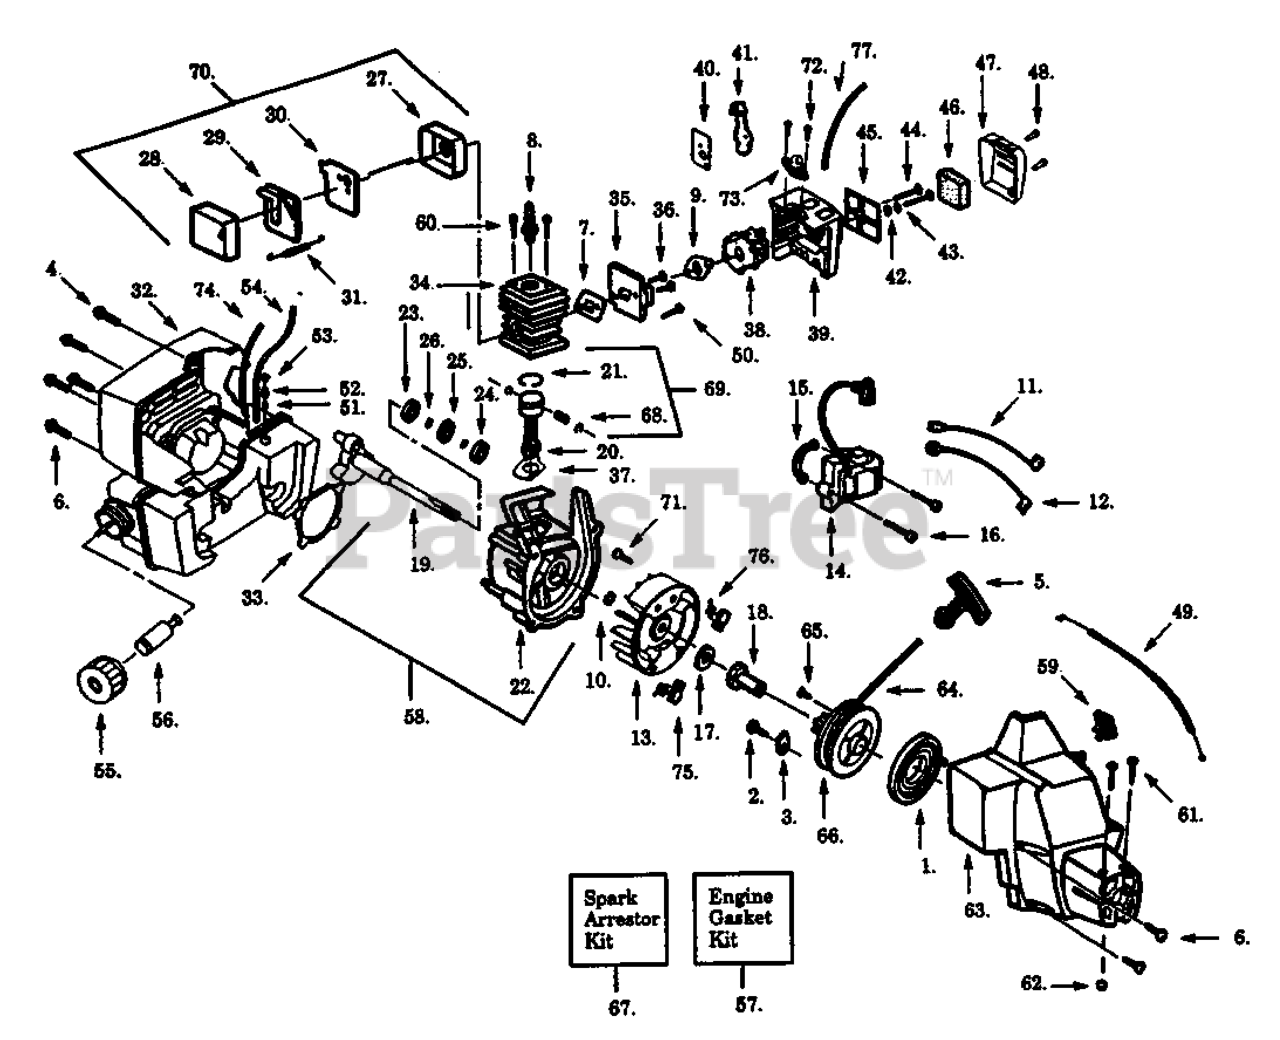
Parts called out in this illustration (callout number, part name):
1	SPRING-STARTER
2	SCREW 8-16 X 9/16 (PLAS
5	HANDLE-STARTER
6	SCREW - SHROUD
7	GASKET
8	Spark Plug (Model GF26 (RCJ-SY))
9	GASKET - CARBURETOR
12	GROUND WIRE
13	FLYWHEEL
14	IGNITION MODULE
15	SPACER - IGNITION MODULE
17	WASHER FLAT
18	COUPLING-DRIVE
19	Cranshaft Ass'y.
20	CONNECTING ROD ASSEMBLY
21	PISTON RING
22	CRANKCASE ASSY
25	SEALING RING
26	RETAINING RING
27	MUFFLER BODY
28	MUFFLER COVER
29	MUFFLER BAFFLE - EXIT
30	MUFFLER BAFFLE - FIRST
31	MUFFLER SPRING
32	Shroud & Tank Amy.
33	GASKET, CRANKCASE
34	CYLINDER
35	CARB. ADAPTER
36	SCREW - CARB. ADAPTOR
37	GASKET - CYLINDER
38	CARBURETOR
40	CHOKE PLATE
41	CHOKE SHUTTER
43	CHOKE SPACER
45	FILTER PLATE
46	AIR FILTER FOAM
47	AIR FILTER COVER
48	SCREW - THROTTLE HOUSING
49	THROTTLE CABLE
51	VALVE-CHECK (DUCKBILL)
54	FUEL LINE - PRIM/TNK
55	CAP ASSY W/ RETAINER
56	FUEL PICK UP ASSY
57	ENGINE GASKET KIT
58	C'case & C'shaft Ass'y.
59	SWITCH
61	SCREW - PINCH CLAMP
62	LOCKNUT-HEX 10-24
63	FAN HOUSING/SHROUD ASSEMBLY
66	Starter Pulley
67	KIT-SPARK ARRESTOR (OLD STYLE)
68	WRIST PIN RET.
69	PISTON KIT
70	MUFFLER KIT
72	SCREW - PRIMER ASSEMBLY
73	PRIMER BULB ASSEMBLY
74	HOSE. FUEL
75	Starter Dog
76	STARTER DOG SPRING
77	KIT.LINE TANK/PURGE
